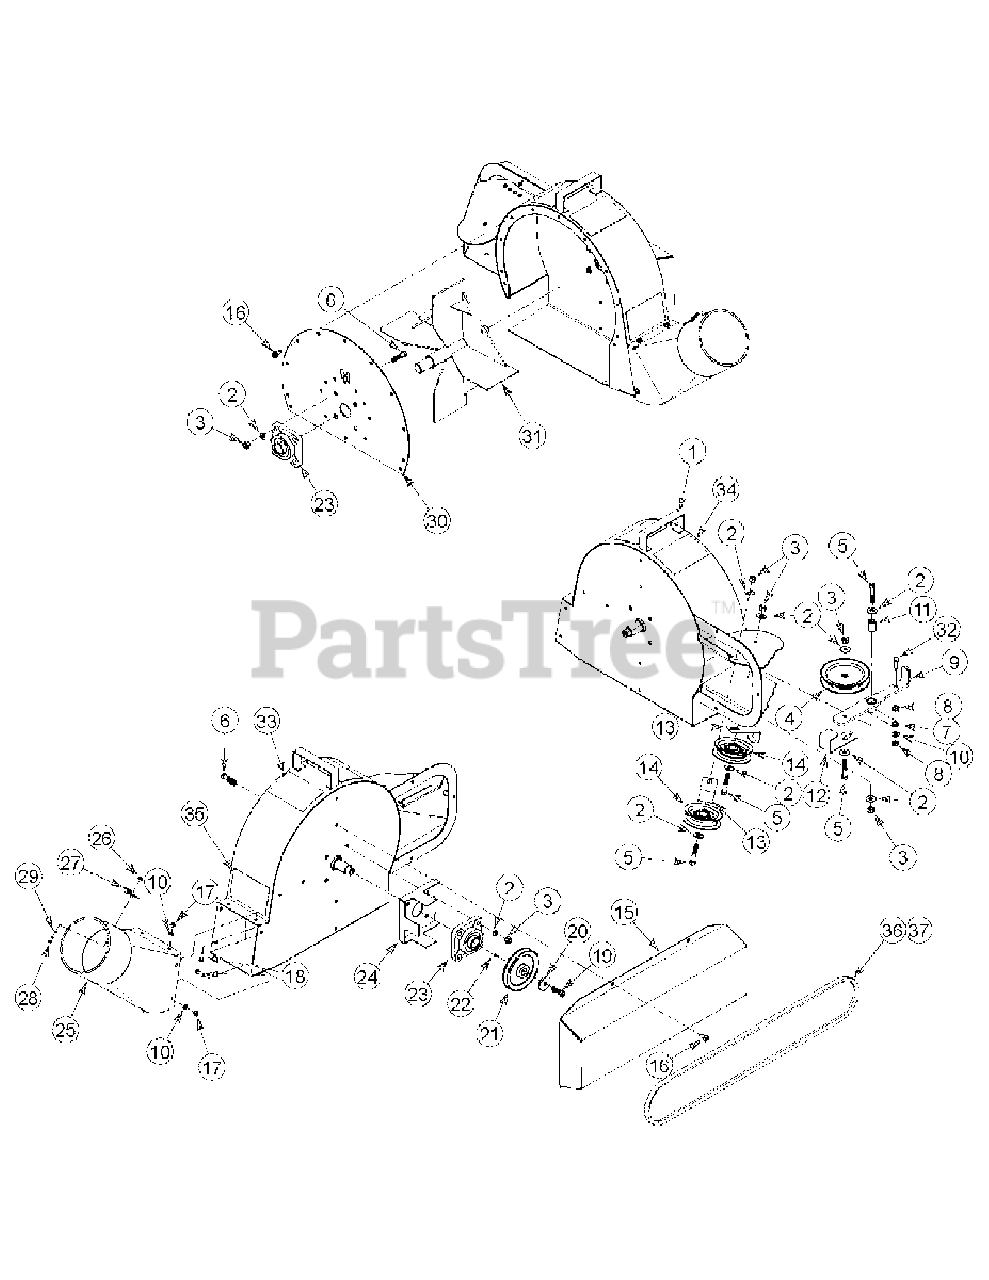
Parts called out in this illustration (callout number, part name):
1	BLOWER HOUSING
2	FLAT WASHER 5/16"
3	HEX NUT, NYLON INSERT 3/8"-16
4	IDLER PULLEY
5	CAP SCREW 3/8"-16 X 2" LONG
6	CAP SCREW 3/8"-16 X 1 1/2" LONG G5
8	HEX NUT, NYLON INSERT 5/16"-18
9	BELT TENSIONING ASSEMBLY
10	FLAT WASHER 1/4" USS
11	BELT TENSIONING BUSHING
12	BELT GUIDE, LARGE PULLEY
13	BELT GUIDE SMALL PULLEY
14	BACK SIDE BELT IDLER PULLEY
15	BELT COVER
16	SELF THREADING SCREW UNSLOTTED 5/16"-18 X 5/8" LONG
17	HEX NUT, NYLON INSERT 1/4"-20
18	CAP SCREW 1/4"-20 X 3/4LONG
19	BOLT, SERRATED FLANGE 3/8"-16 X 1.25" LONG
20	FLAT WASHER HEAVY
21	DRIVE PULLEY
24	BELT GUIDE
25	TRANSITION CHUTE
26	HEX NUT, NYLON INSERT, #10-24
27	SPRING CLIP
28	MACHINE SCREW #10-24X 1/2" LONG
29	FLAT WASHER #10 FENDER
30	BLOWER COVER
32	CAP SCREW 5/16"-18 X 1" LONG
33	LABEL, DANGER TURN OFF MOWER
34	LABEL, DANGER ROTATING BLADES
35	LABEL, DANGER THROWN OBJECT
36	BELT 48" DECK
37	BELT 54" DECK
37	BELT 60" DECK
